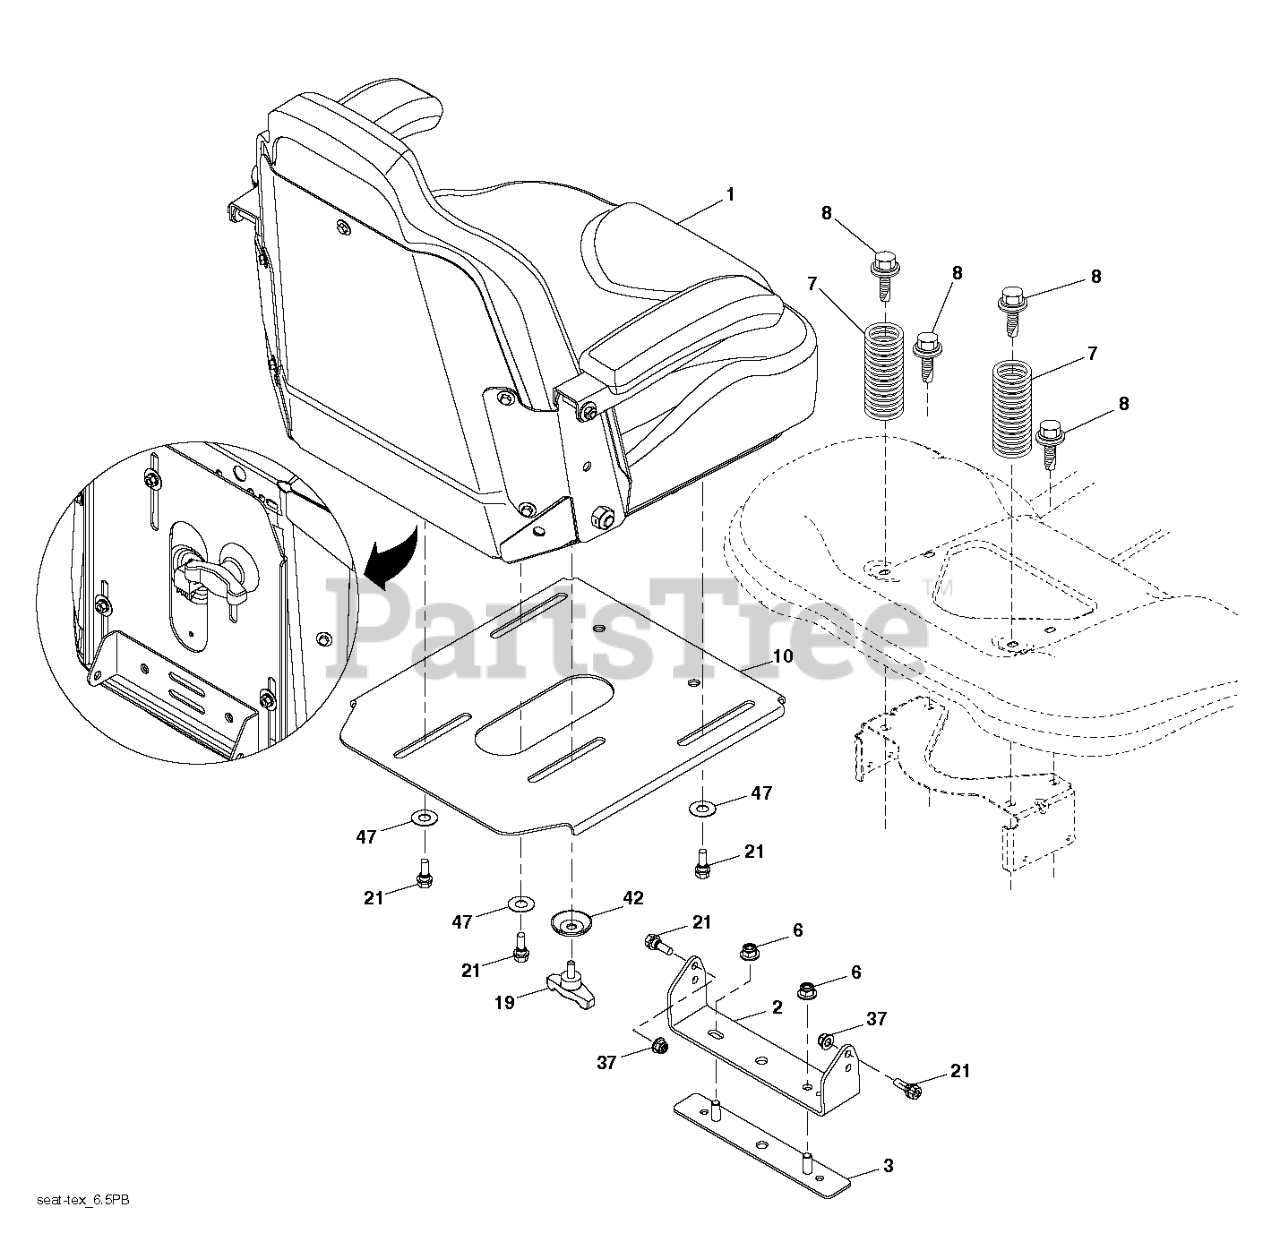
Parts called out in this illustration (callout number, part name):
1	SEAT TRACTOR MZ
2	BRACKET PIVOT FENDER SEAT TRAC
3	BRACKET ASSEMBLY REINFORCEMENT
6	NUT 3/8-16 HEX FLG NYLOC ZD
7	SPRING COMPRESSION SEAT 300 SE
8	BOLT.5/16-18UNCX3/4 W/SEMS.BLK
10	BRACKET ASM PLATE & BRACKET SE
19	KNOB SEAT 5/16-18X3/4
21	BOLT SHOULDER 5/16-18 UNC
37	5/16-18 NYLOC FLANGE NUT
42	WASHER.CUP.SEAT.
47	WASHER NYLON .50 X 1.00 X .045
